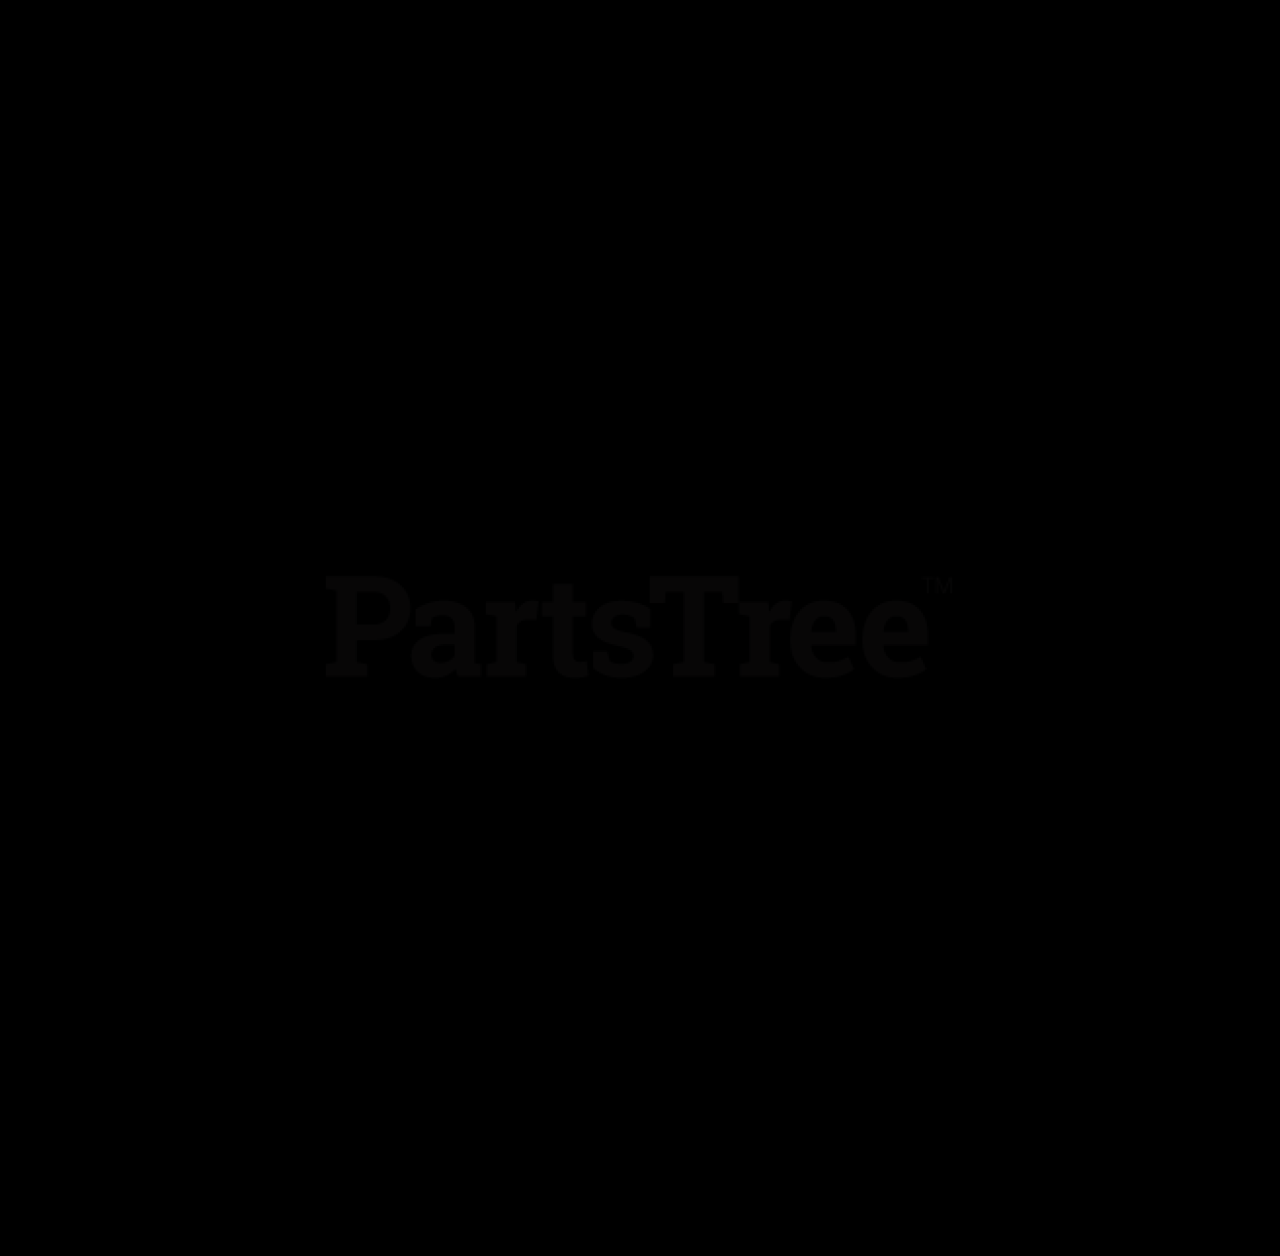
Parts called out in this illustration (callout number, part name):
1	Switch, Ignition
2	Harness, Wiring
3	Weldment, Battery Support
4	Screw, Tapping .38-16 x .75 Hex Washer Head
5	Key, with Cap
6	Hour Meter w/ Maintenance
7	Switch, Clutch With Retainer Ring
8	Light, Indicator
10	Nut, Locking Top Flange .31-18
11	Gauge, Temperature
12	Bracket, Battery Hold-Down
13	Bolt, Hex .25-20 x .75 Grade 5
14	Mount, Safety Switch
15	Cable, Positive Battery with Boots
16	Cable, Negative Battery
17	Cable Tie
18	Screw, Machine 10-24 x .75 Hex Washer Head
19	Nut, Locking Nylon 10-24 With Insert
20	Boot Terminal, Red
21	Switch, Snap Mounting (N.O.) (Included with Seat)
22	Switch, Single Pole
23	Screw, Machine 10-24 x .75 Hex Washer Head
24	Screw, Tapping .25-20 x .50 Hex Washer Head
25	Washer, Flat-Steel .406 x 1.00 x ..083
26	Diode, Connector Shell
27	Relay (Included with Harness)
28	Fuse, ATO 30 Amp (Included with Harness)
29	Pre-Heat Timer (Included with Engine)
30	Fuse, ATO 60 Amp (Included with Harness)
31	Battery Terminal Boot, Red
